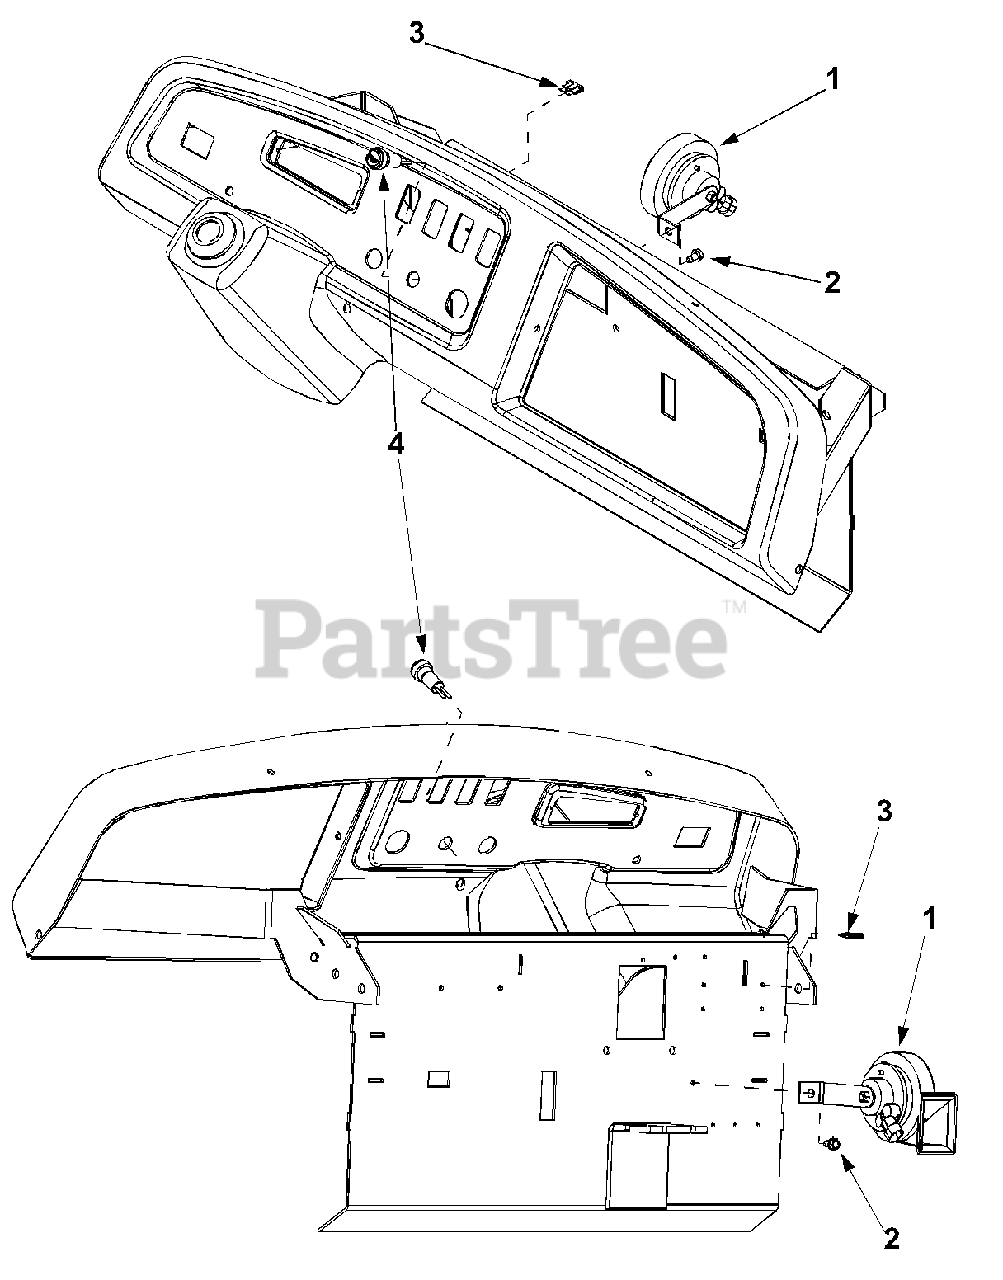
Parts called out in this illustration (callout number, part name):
1	Horn 12V
2	Hex Washer Screw 1/4-20 x .500
3	Fuse 5 amp
4	Horn Switch
